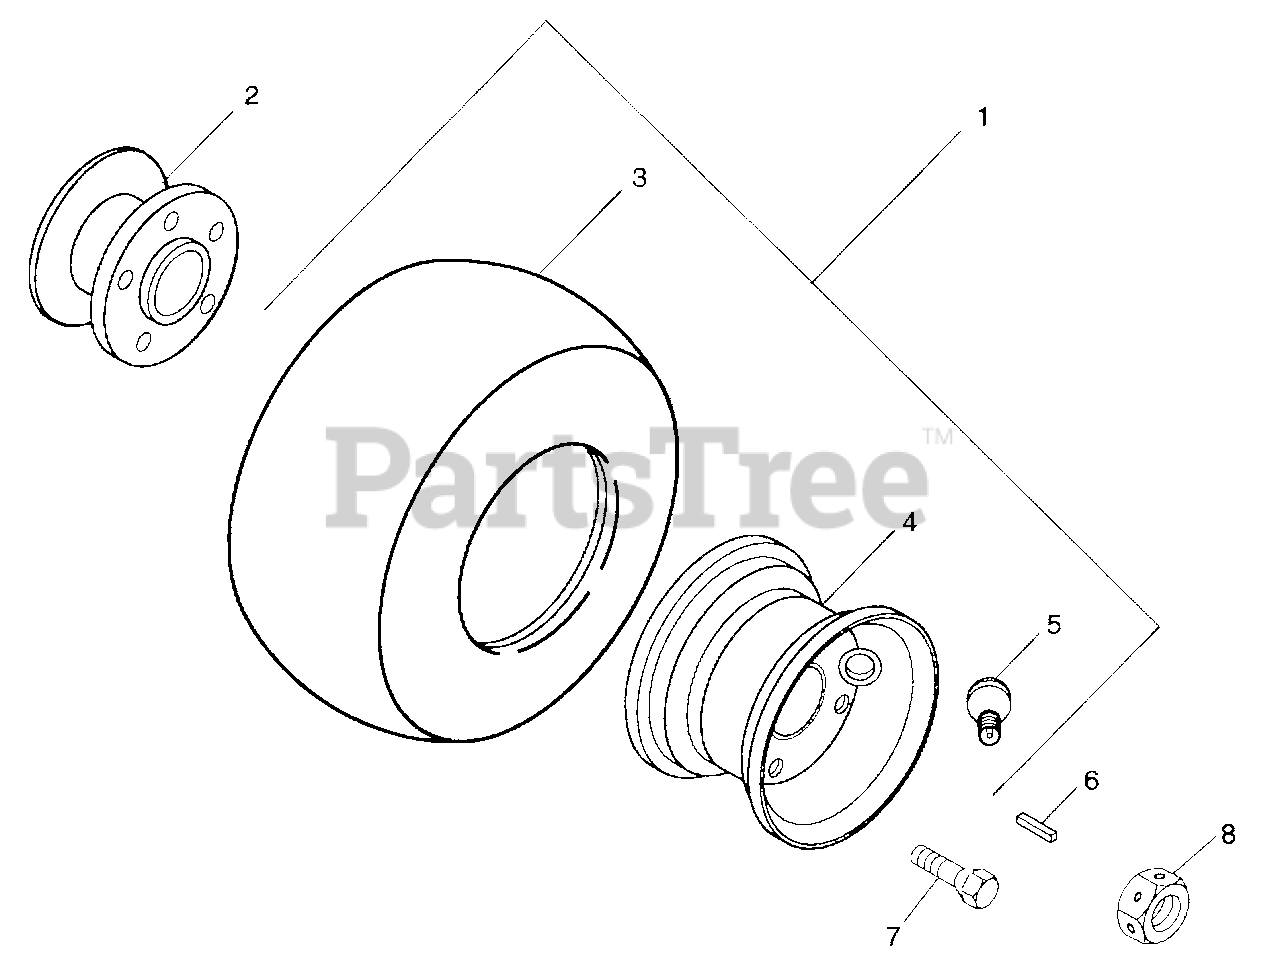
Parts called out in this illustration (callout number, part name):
1	T/WHL ASSSY 20 X 10-10 TURF TRAC RS
2	HUB, DISC BRAKE
3	TIRE 20 X 10.00-10 TURF TRAC RS
4	WHL, 10.00 X 7.75 DICO2500
5	VALVE STEM ASS'Y
6	KEY, RECT .313 X .275 X .932
7	BLT .44-20 X 1.0
8	NUT-PACK 1.00-20 ENF
